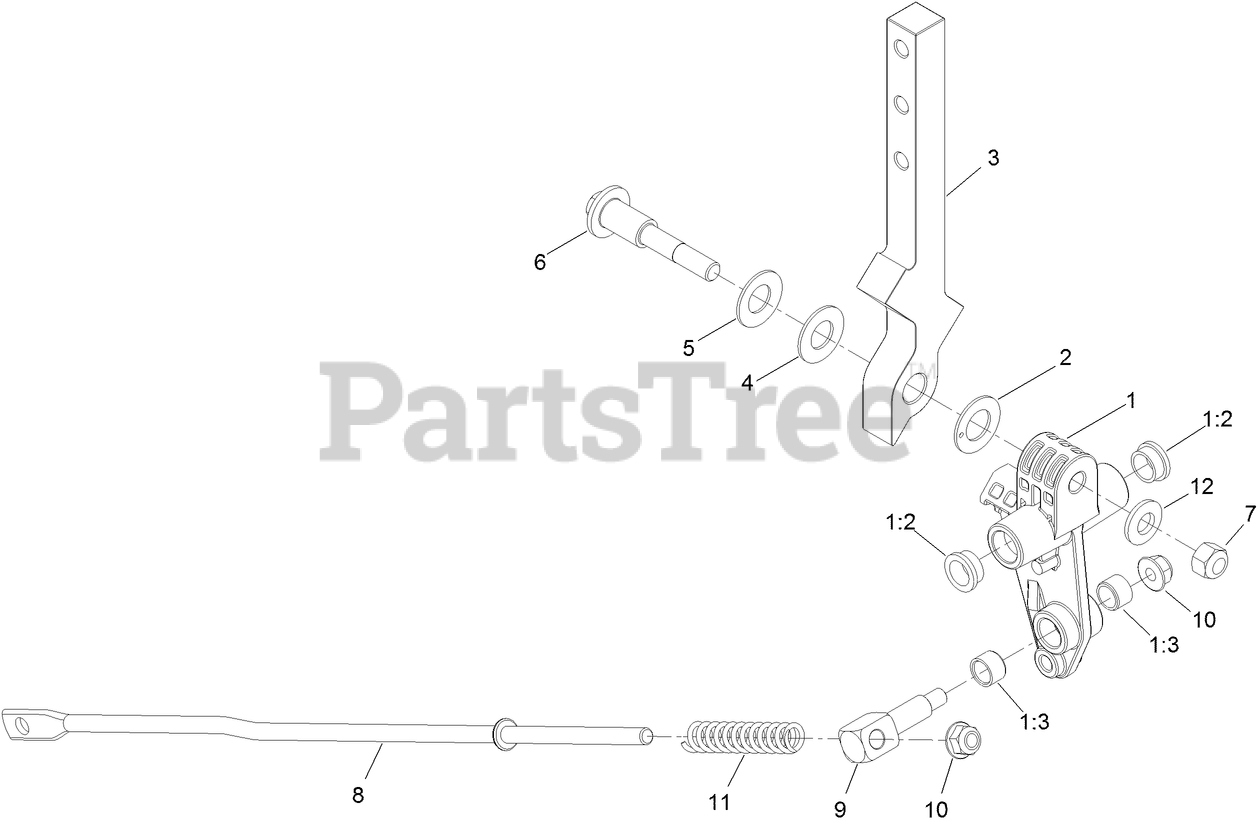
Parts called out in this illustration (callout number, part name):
1	CONTROL ARM ASM
1:2	BUSHING
1:3	BUSHING-SLEEVE
2	WASHER-FRICTION
3	ARM-CONTROL
4	WASHER
5	WASHER-BELLEVILLE
6	BOLT-PIVOT
7	NUT-LOCK, CONE
8	LINK-CONTROL
9	SWIVEL
10	NUT-HF, NI
11	SPRING-RETURN, NEUTRAL
12	WASHER-FLAT
